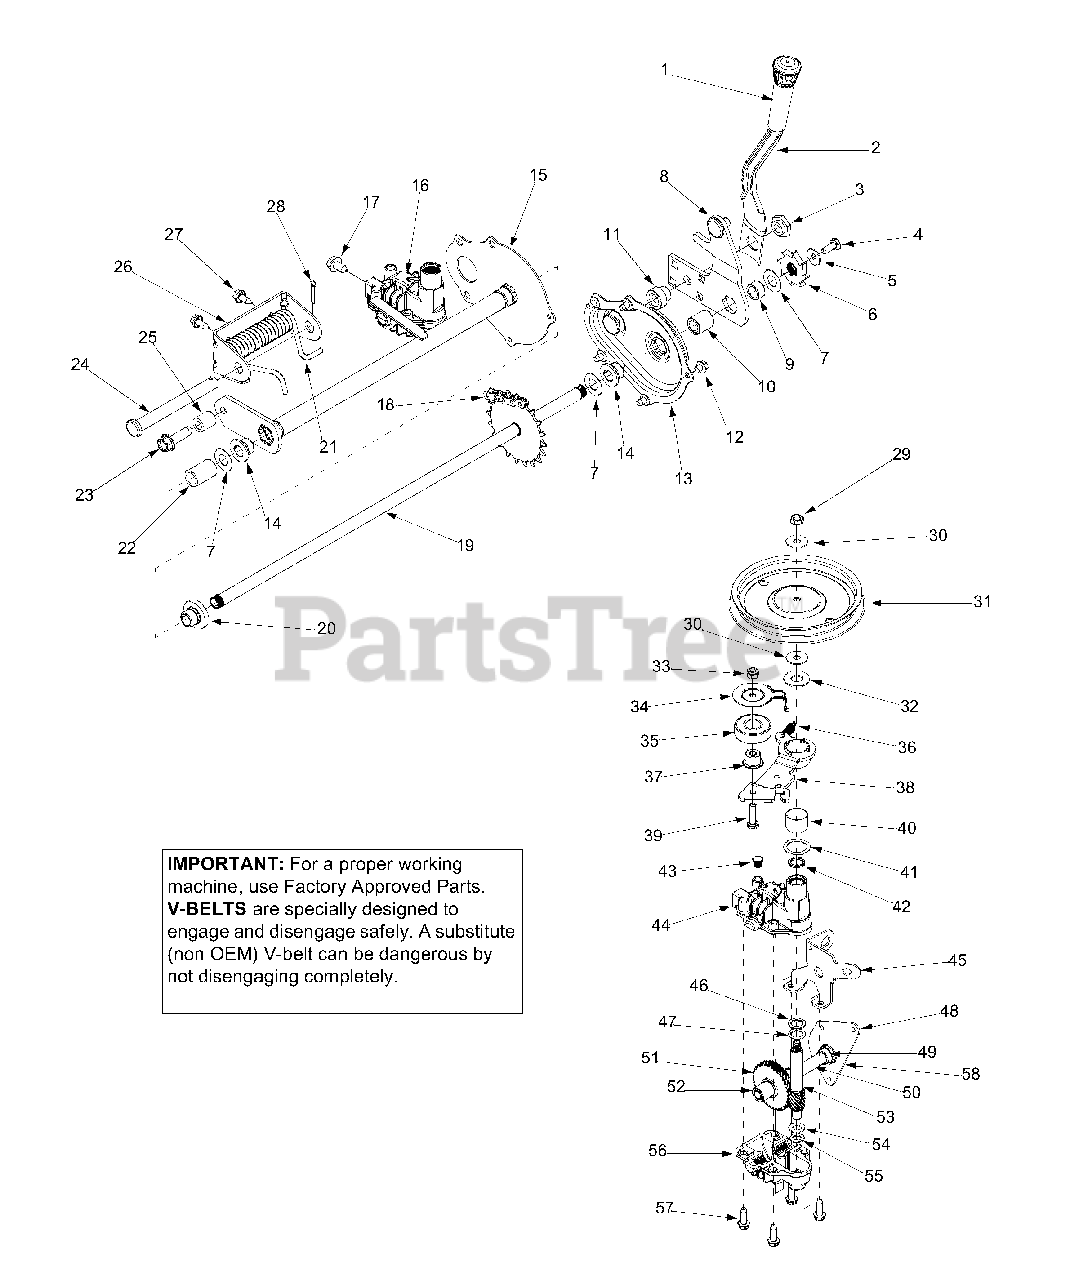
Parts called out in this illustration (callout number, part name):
2	Spring Lever
3	Shoulder Nut .825 x .165 Lg.
4	Cap Screw 1/4-20 x .620
5	Bell Washer .285 ID x .75 OD
6	Wheel Rachet
7	Flat Washer .508 ID x 1.0 OD
9	Spacer .510 ID x .70 OD
10	Sleeve Bearing .504 ID x .830 OD
11	Shoulder
12	Tap Screw 1/4-20 x .375
16	Transmission Assembly
17	Hex Screw 5/16-18
18	Chain
19	Rear Axle Assembly
20	Flange Bearing .506 ID x .715 Lg
21	Torsion Spring
22	Spacer .550 ID x .750 OD
23	Screw 3/8-16 x .25
24	Clevis Pin .50 Dia x 4.82 Lg.
25	Spacer .385 ID x .624 OD
28	Cotter Pin
29	Hex Jam Nut 5/16-24
30	Bell Washer .325 ID x .930 OD
32	Flat Washer .510 ID x 1.120 OD
33	Hex Jam Nut 1/4-28
34	Belt Keeper
35	Bearing
36	Extension Spring
37	Flange Spacer
38	Idler Bracket Assembly
39	Hex Cap Screw 1/4-28 x 1.0
40	Bearing Sleeve
41	Flat Washer .885 ID x 1.45 OD
42	Oil Seal
44	Upper Housing Assembly
47	Thrust Washer .504 ID x .70 OD
48	Pivot Bracket
49	Flange Bearing
50	Output Shaft 6T
52	Bearing
53	Pinion Shaft 10T
54	Thrust Washer 3/8 x .70
55	Thrust Washer .388 x .625
56	Lower Housing Assembly
57	Hex Screw 1/2-20 x .75
58	Shaft Assembly
